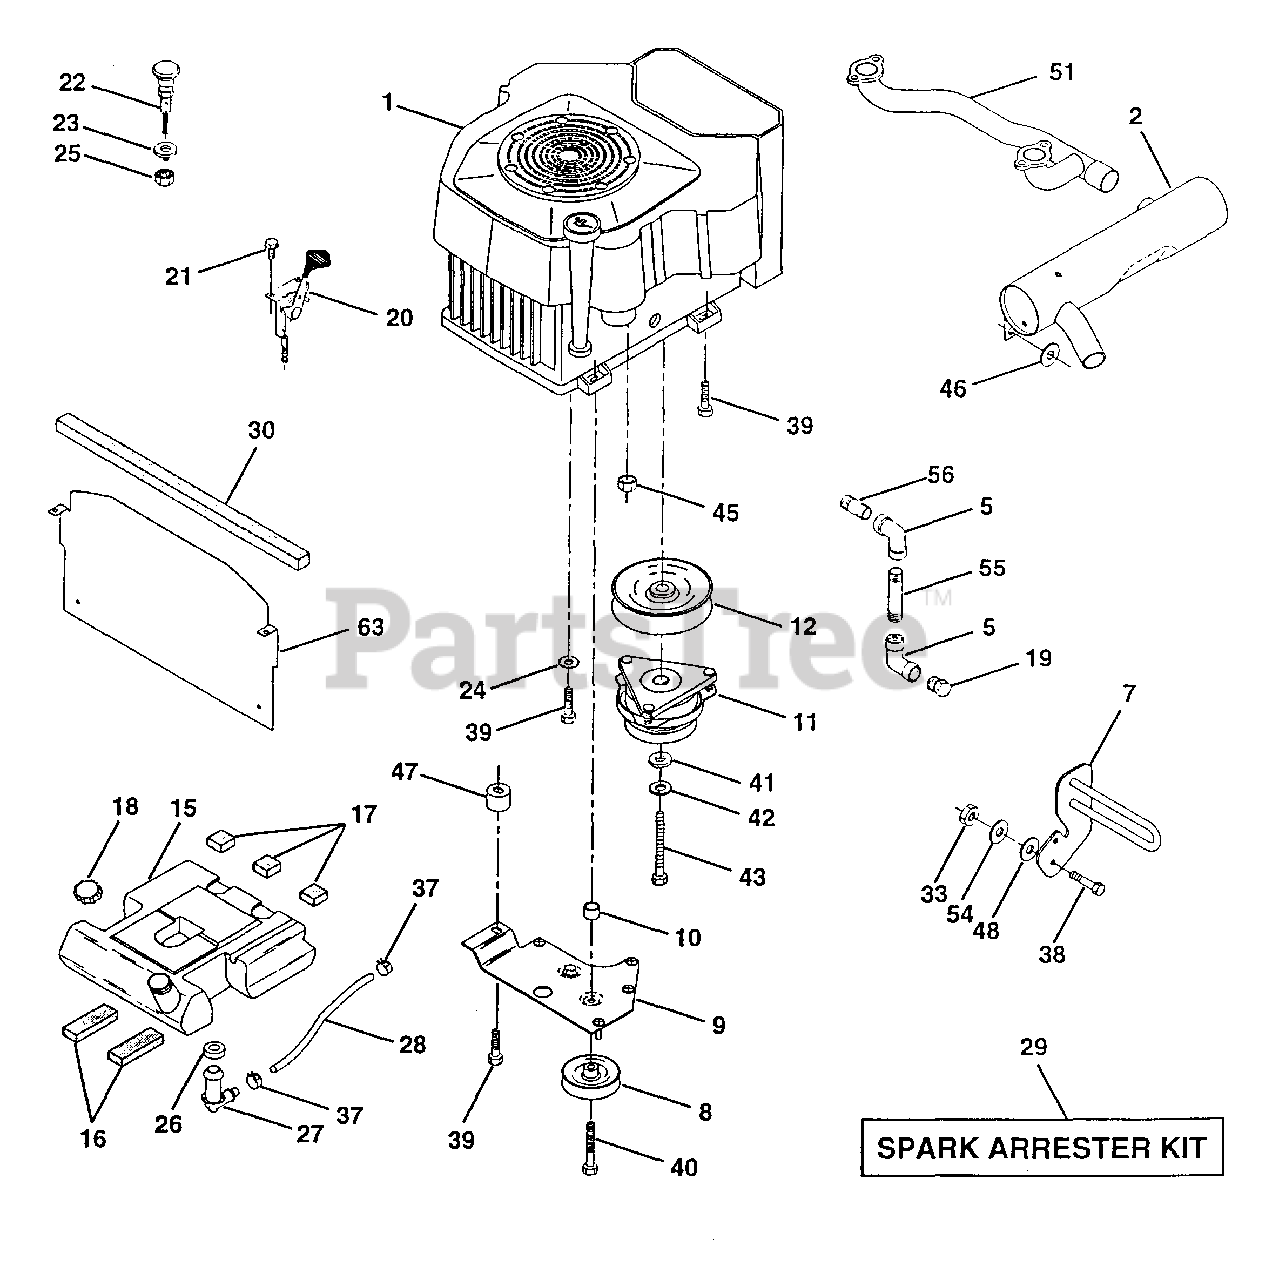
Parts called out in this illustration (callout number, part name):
2	Muffler VGT Cylinder
5	Elbow STD 90 Degree 3/8-18 NPT
7	Muffler Assembly Guard
8	Pulley V-Idler (AYP part number)
9	Keeper Asm. Belt Engine VGT (AYP part number)
10	Bushing
11	Clutch Electric (AYP part number)
12	Pulley Engine VGT Elect Clutch
15	Tank Fuel Rear 3.50
16	Pad Spacer
17	Pad Spacer
18	Cap Asm Fuel W/Sym Vented
19	Plug Oil Drain
20	Control Throttle (AYP part number)
21	Screw Hex Thd Cut 1/4-20 X 5/8
22	Control Choke
23	Washer 13/32 X 13/16 x 16 Ga
24	Washer Ext Tooth 3/8
25	Nut Keps 3/8-24 Unf
26	Bushing
27	Stem Tank Fuel
28	Fuel line (AYP part number)
29	Spark Arrester Kit
30	Strip Foam 18"
33	Nut, Hex W/Ins. 3/8-16 UNC
37	Clamp Hose
38	Bolt, Fin Hex 3/8-16 UNC x 1-1/2
39	Screw TT 3/8-16 x 2-1/4 UNC
40	Screw TT 3/8-16 x 4 UNC
41	Washer 1-1/2 OD X 15/32 ID X .250
42	Washer Lock 7/16
43	Bolt Hex 7/16-20 X 4-1/4 Ga 5
45	Nut Flange 1/4-20 Starter Nut
46	Washer 13/32 x 1 x 16 Ga.
47	Spacer Engine CV22 Round PM
48	Washer 13/32 x 1-1/4 x 7 Ga.
51	Pipe Crossover CV22
54	Washer Flat 13/32 x 7/8 x 14 Ga.
55	Nipple, Pipe 3/8 NPT x 4-1/2
56	Nipple, Pipe 3/8 NPT x 1.00
63	Shield, Heat VGT 22 HP YP/Husq.
